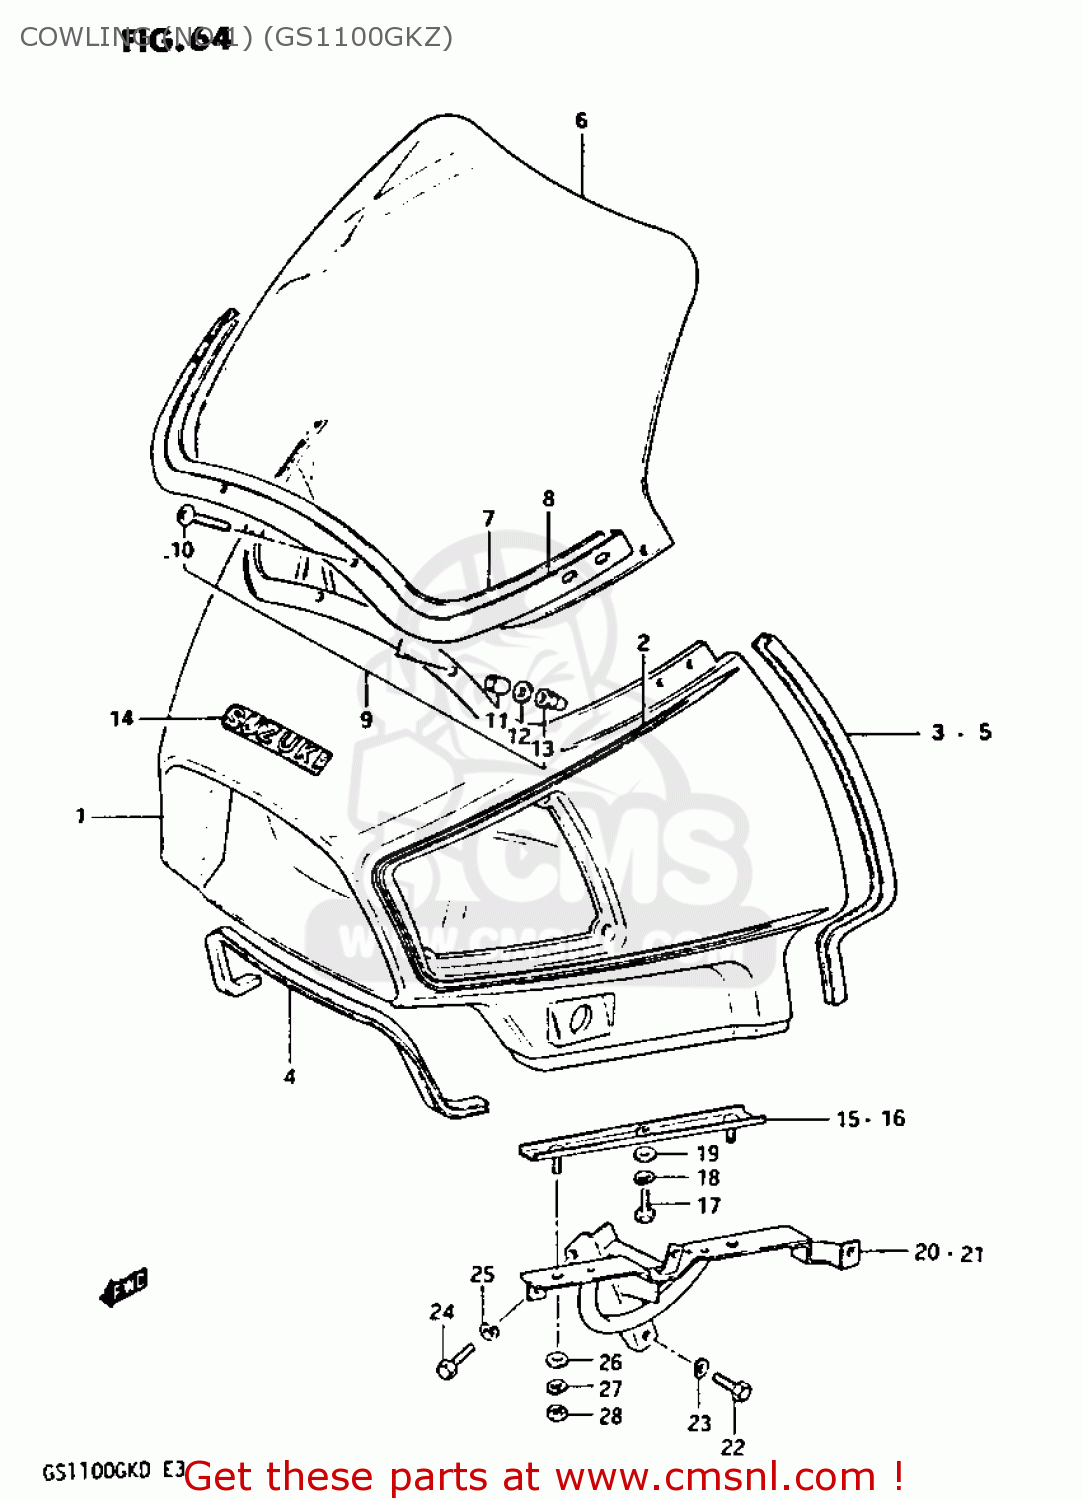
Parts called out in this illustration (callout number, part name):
1	COWLING ASSEMBLY
2	TAPE SET,COWLING
3	MOLDING,COWLING,RIGHT
4	MOLDING,LOWER
5	MOLDING,COWLING,LEFT
6	WINDSHEILD,COWLING
7	CUSHION,WINDSHEILD
8	PLATE,WINDSHEILD
9	BODY ASSEMBLY,COWLING
10	SCREW
11	SPACER(6.3X9.3X16.5)
12	WASHER (6.5X20X1.2)
13	NUT
14	EMBLEM,COWLING
15	PLATE,COWLING FITTING
16	PLATE,COWLING FITTING
17	BOLT
18	WASHER,LOCK
19	WASHER
20	BRACE,COWLING
21	BRACKET,COWLING,LEFT
22	BOLT
23	LOCK WASHER
24	BOLT
25	LOCK WASHER
26	WASHER
27	LOCK WASHER
28	NUT
